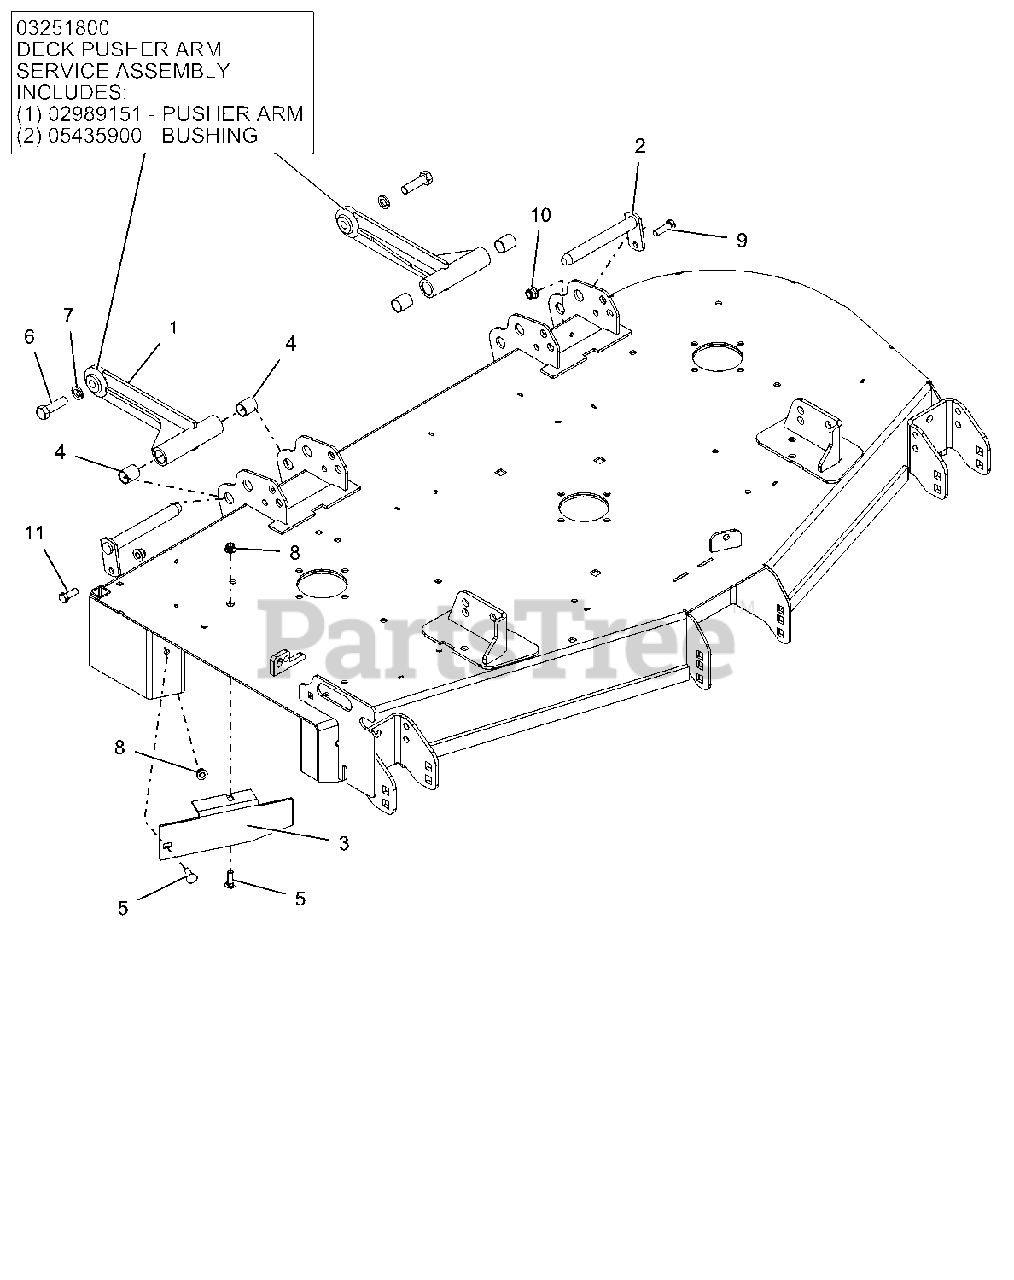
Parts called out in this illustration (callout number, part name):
1	BRG, .750 X .875 X 1.000
1	DECK PUSHER ARM WMT - BLACK
1	DECK PUSHER ARM ASSEMBLY
2	WELDMENT, MOWER MTG. PIN
3	BAFFLE, DISCHARGE, 52"
4	BRG, .750 X .875 X 1.000
5	@BLT-RDHDSQNK .31-18X1.00 G5YZ
6	BLT-HEX .50-13X1.75 GR5EP80 YZ
7	@WSHR-LK .50X.125 REG YWZC
8	@NUT-LK-NYL-FLG .31-18 YWZC
9	@BLT-HEX .38-16X1.25 GR5 YWZC
10	@NUT-LK-NYL-FLG .38-16 YWZC
11	@BLT-HEX .38-16X1.00 GR5 YWZC
